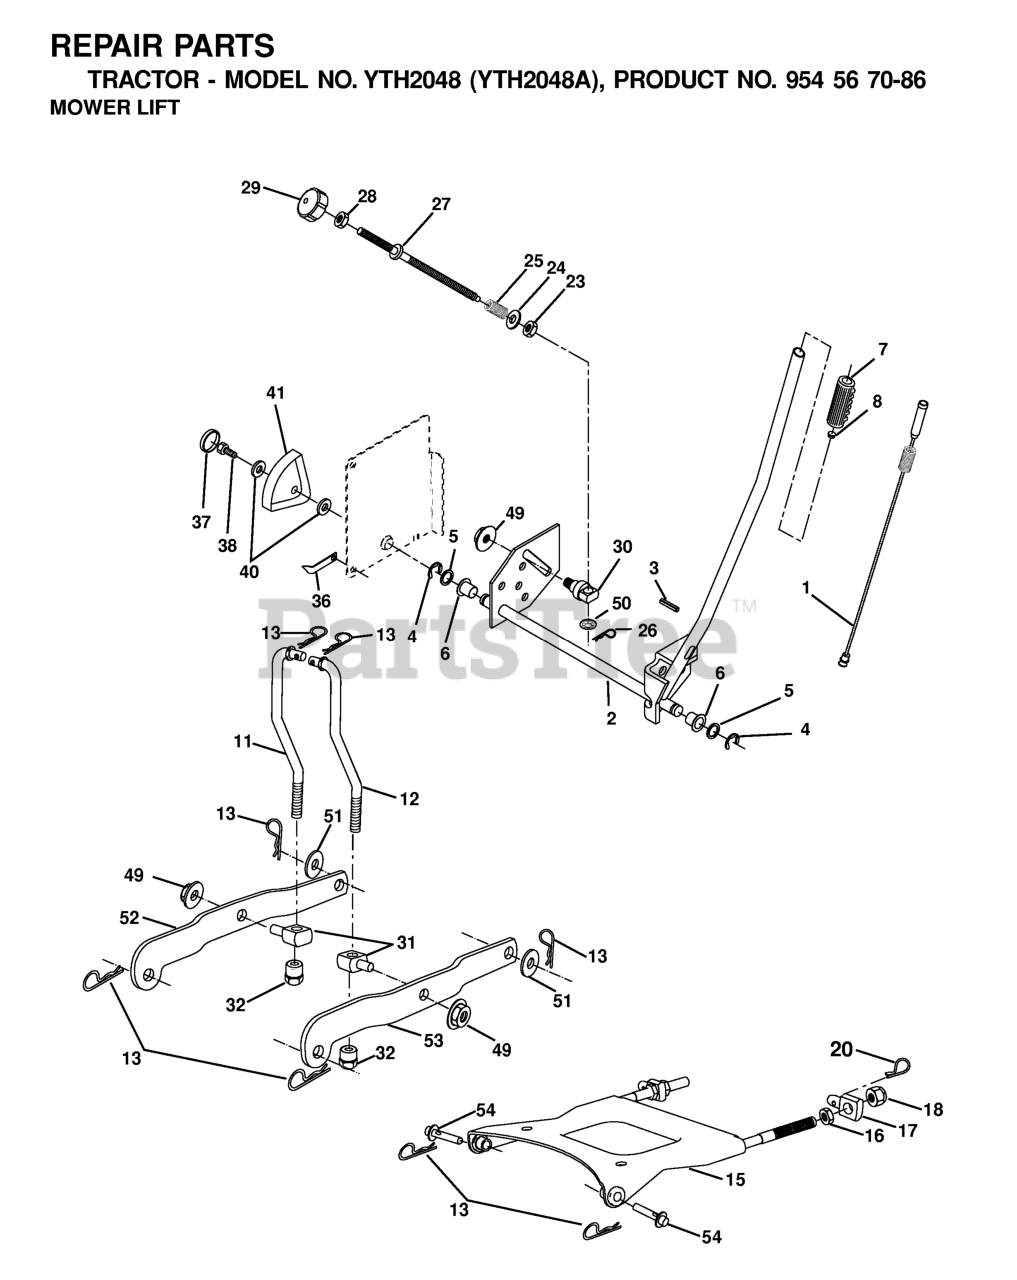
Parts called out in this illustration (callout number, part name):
1	WIRE ASM INNER W/ PLUNGER LT
2	SHAFT ASM R HANDLE
3	PIN GROOVE.
4	RETAINING RING LT
6	BEARING.NYLON
7	GRIP HANDLE
8	PLUNGER BUT KIT
11	LIFT LINK LH
12	LIFT LINK RH
13	RETAINER-SPRNG RB
15	PLATE ASM SUSP FRONT
16	NUT.HEX.JAM.1/2-13
18	NUT.LK.W/WSH.1/2.
20	SPRING RETAINER
25	SPRING**
26	RETAINER CLIP
27	ROD ADJ LIFT
28	NUT
29	KNOB INF 3/8-16
32	NUT, LIFT LINK 7/16-20
36	POINTER, HEIGHT INDICATOR(2 2)
38	SCREW 5/16-18X1
41	IND. HEIGHT STLT
49	NUT
50	NUT PUSH M
51	Washer 1 17/32 X 7/8 X 16 Ga
52	ARM SUSP. REAR LH
53	ARM SUSP REAR RH
54	PIN.FLANGE
